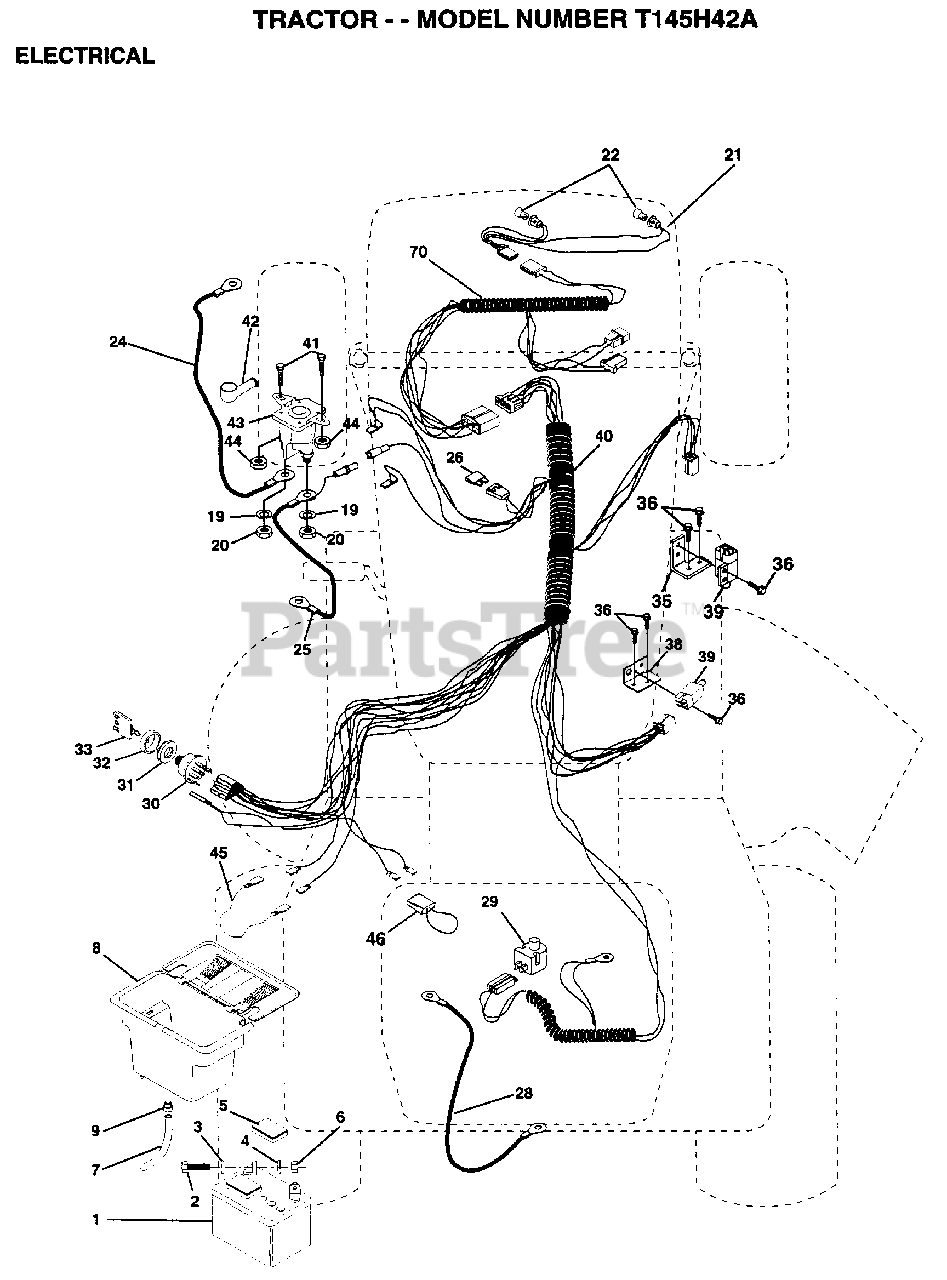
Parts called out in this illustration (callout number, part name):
2	BOLT LT
3	WASHER
4	LOCKWASHER
5	"CAP,BATTERY "
7	TUBE T
9	HOSE CLAMP T
20	NUT
21	"HARNESS,LIGHT SOC"
22	HEADLAMP BULB
24	"CABLE T, BATTERY"
25	CABLE.BTRY.6GA.RD
26	FUSE HYT
28	CABLE T
29	SWITCH SEAT
30	SWITCH IGN 4POS
31	NUT IGNITION
32	COVER KEY SWITCH
33	KEY
35	BRACKET LT
36	SCREW
38	BRACKET SWITCH IN
39	SWITCH INTERLOCKT
41	BOLT.HX.1/4-20
44	NUT
45	ADAPTER AMMETER
46	PROTECTION LOOP
70	HARNESS ENGINE
